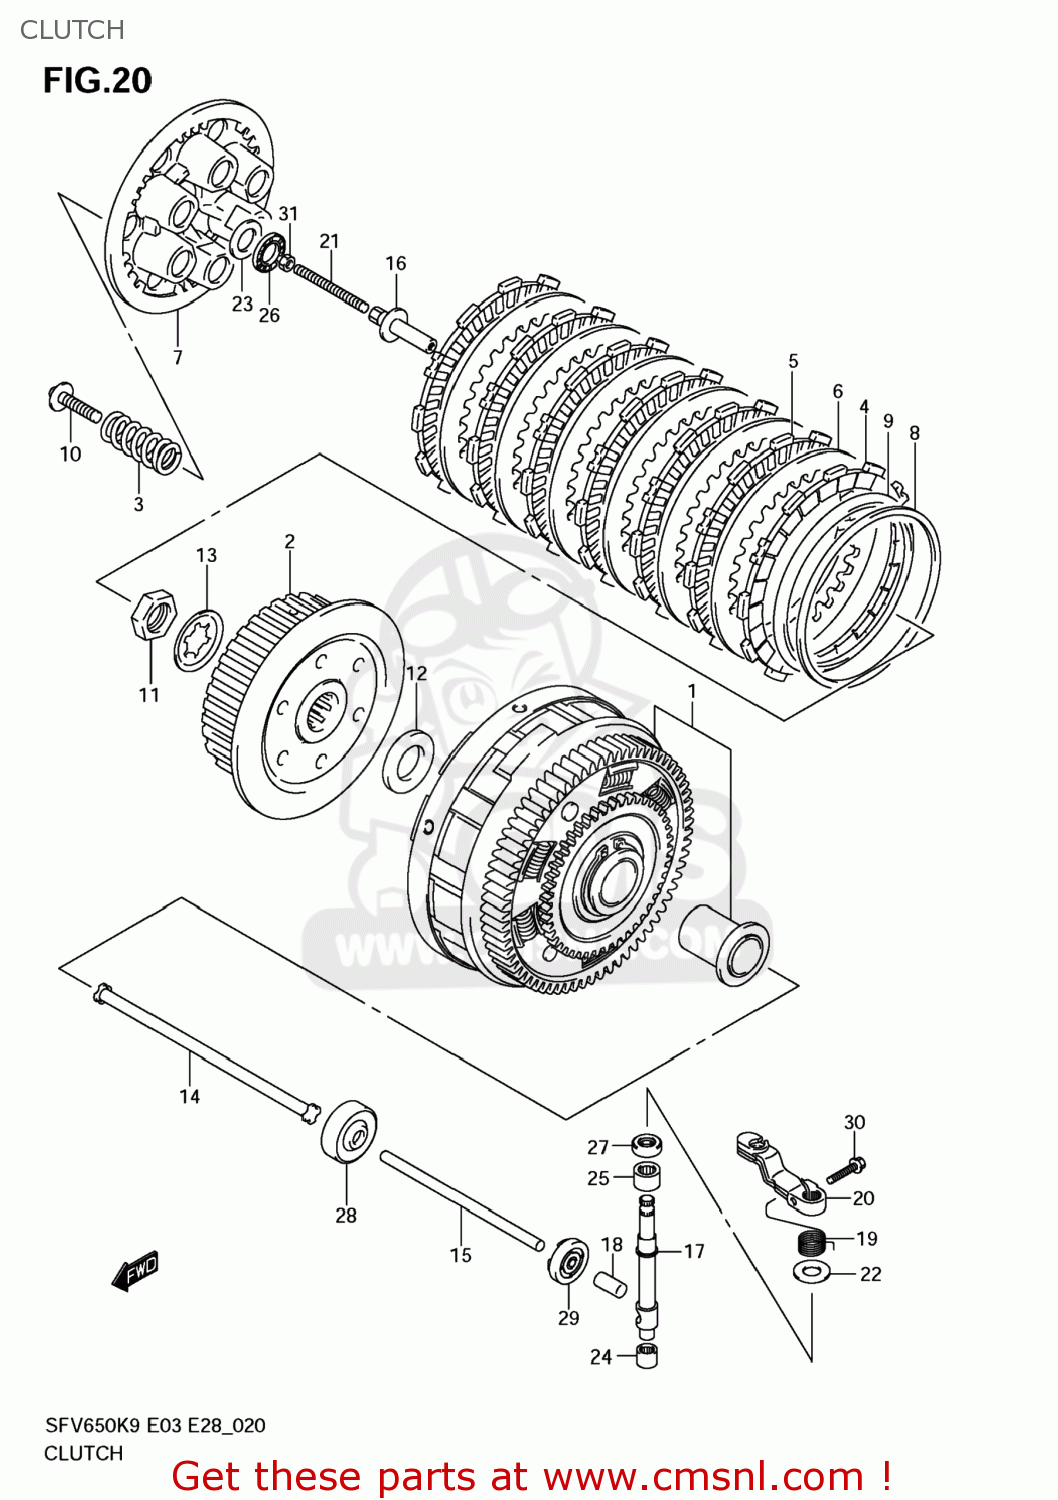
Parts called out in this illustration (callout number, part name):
1	GEAR ASSY,PRI DRIVEN
2	HUB,CLUTCH SLEEVE
3	SPRING,CLUTCH
4	PLATE,CLUTCH DRIVE NO.2 (NAS)
5	PLATE,CLUTCH DRIVE (NAS)
6	PLATE,CLUTCH DRIVEN(T:1.6) (NAS)
7	DISC,CLUTCH PRESSURE
8	SEAT,WAVE WASHER
9	WASHER,CLUTCH PLATE WAVE
10	BOLT(6X30)
11	NUT
12	WASHER(20X36X3)
13	WASHER,LOCK
14	ROD,PUSH,R
15	ROD,CLUTCH PUSH,L
16	PIECE,CLUTCH PUSH
17	CAMSHAFT,CLUTCH RELEASE
18	CAP,CLUTCH PUSH ROD
19	SPRING,CLUTCH RELEASE RETURN
20	ARM,CLUTCH RELEASE
21	SCREW(6X73)
22	WASHER(10.5X24X1)
23	WASHER(15.5X28X1)
24	BEARING(10X14X10)
25	BEARING(12X18X12)
26	BEARING(15X28X2)
27	SEAL,OIL(10X20X6)
28	SEAL,OIL(6X34X10.5)
29	SEAL,OIL(10X17X5)
30	BOLT(6X20)
31	NUT
